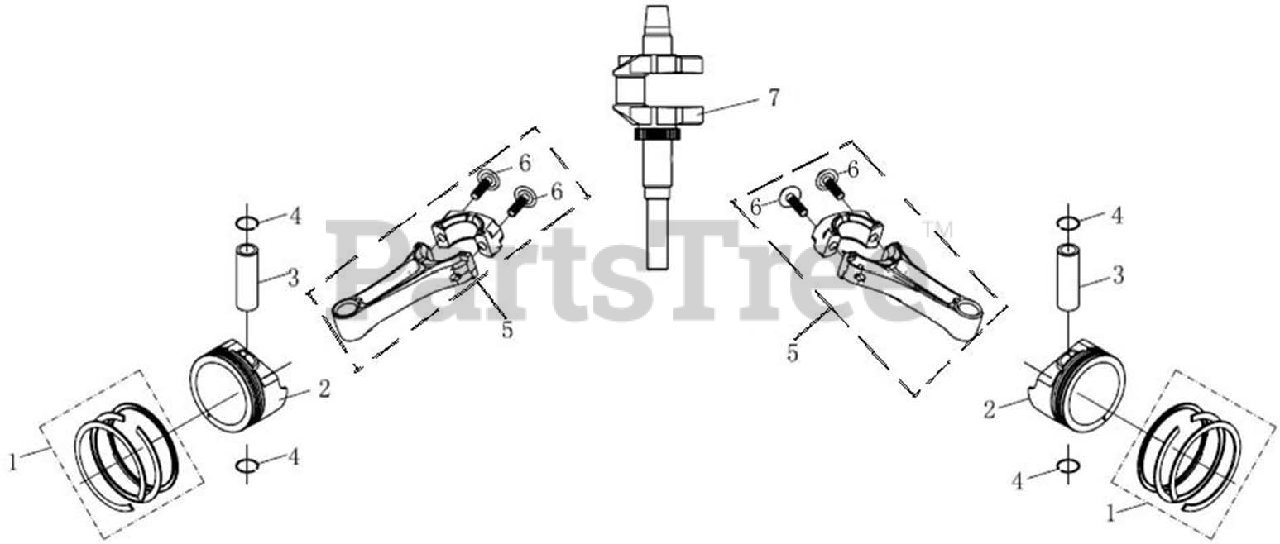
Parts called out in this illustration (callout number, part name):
1	PISTON RING COMBINATION
3	PISTON PIN
4	STEEL CABLE BAFFLE RING
5	CONNECTING ROD, WITH BOLTS
6	CONNECTING ROD BOLT
7	CRANKSHAFT
